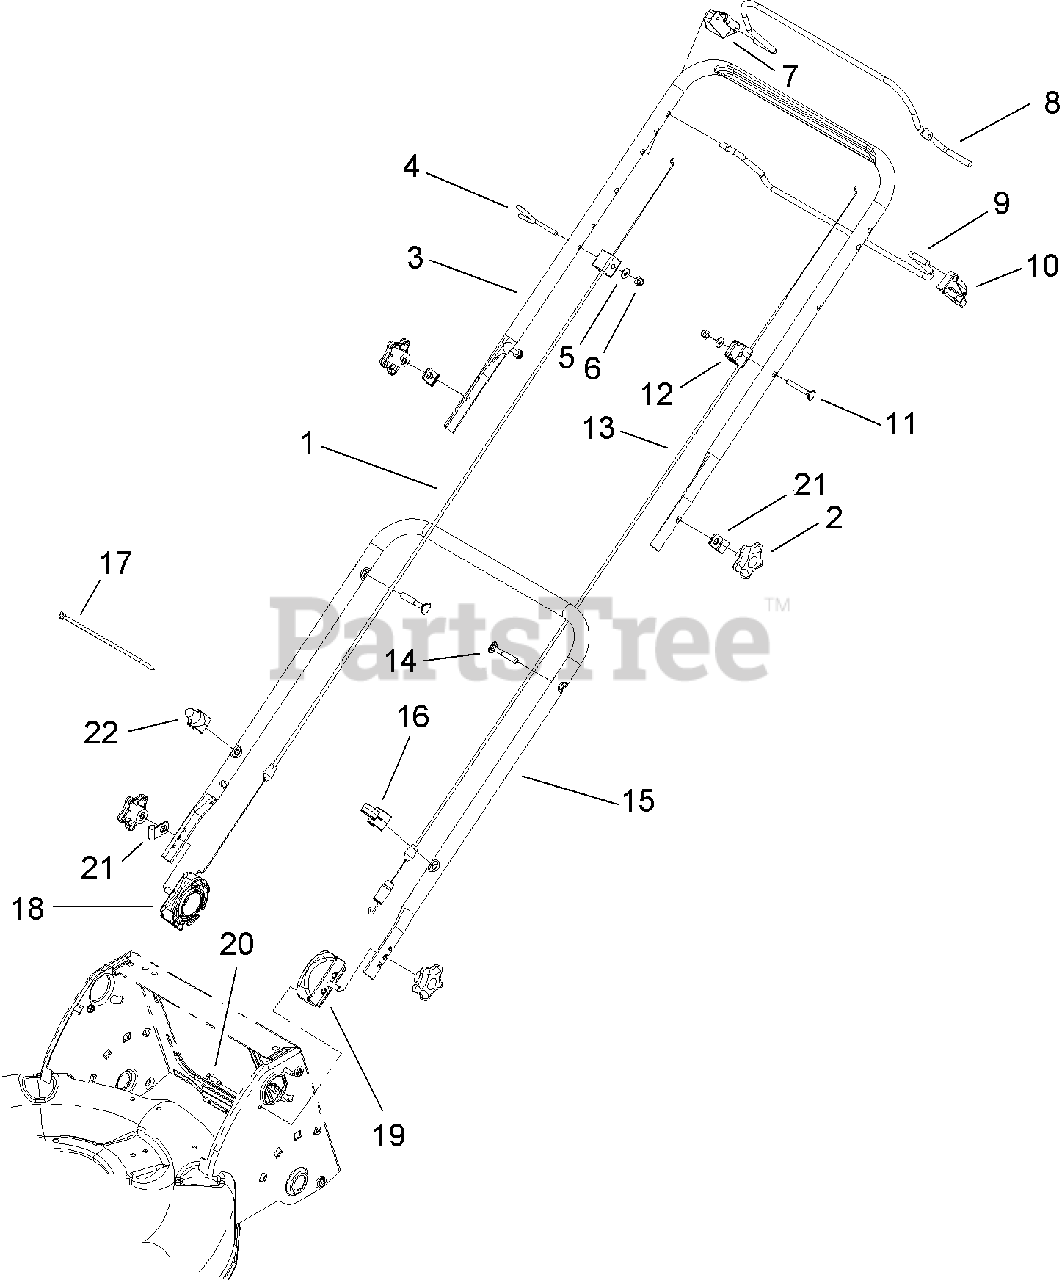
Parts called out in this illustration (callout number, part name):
1	Cable-Brake
2	KNOB-HANDLE
3	Handle-Upper
4	GUIDE-ROPE
5	WASHER-FLAT
6	NUT-LOCK, NI
7	STOP-PIVOT
9	Bail-Control
10	Stop-Pivot
12	ANCHOR-CABLE, UPPER
13	CABLE-TRACTION
14	SCREW-HANDLE
15	HANDLE-LOWER
16	Guide-Cable
17	STRAP-TIE
18	RH HANDLE MOUNT ASM
19	LH HANDLE MOUNT ASM
20	SCREW-HWHTF
22	GUIDE-ROPE, LOWER
